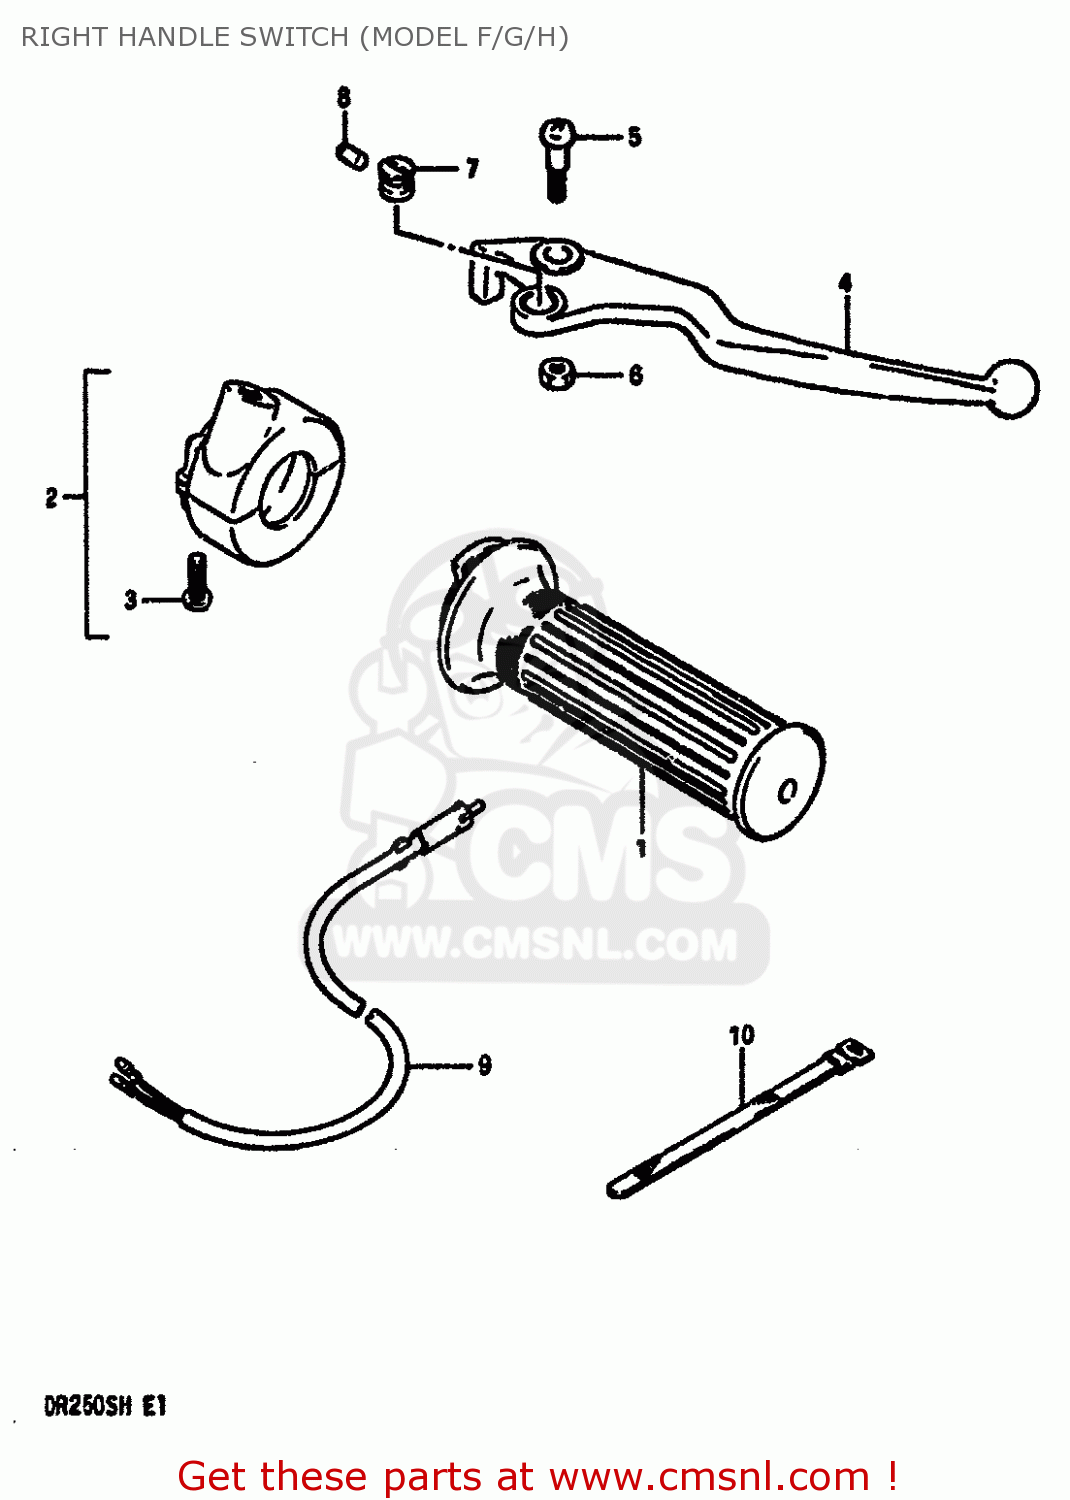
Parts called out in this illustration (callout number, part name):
1	GRIP,THROTTLE
2	CASE ASSY,THROTTLE
3	SCREW 5X20
4	LEVER,BRAKE
5	SCREW
6	NUT 6MM
7	ADJUSTER
8	ROD,PUSH
9	SWITCH ASSEMBLY
10	CLAMP(L:120)
